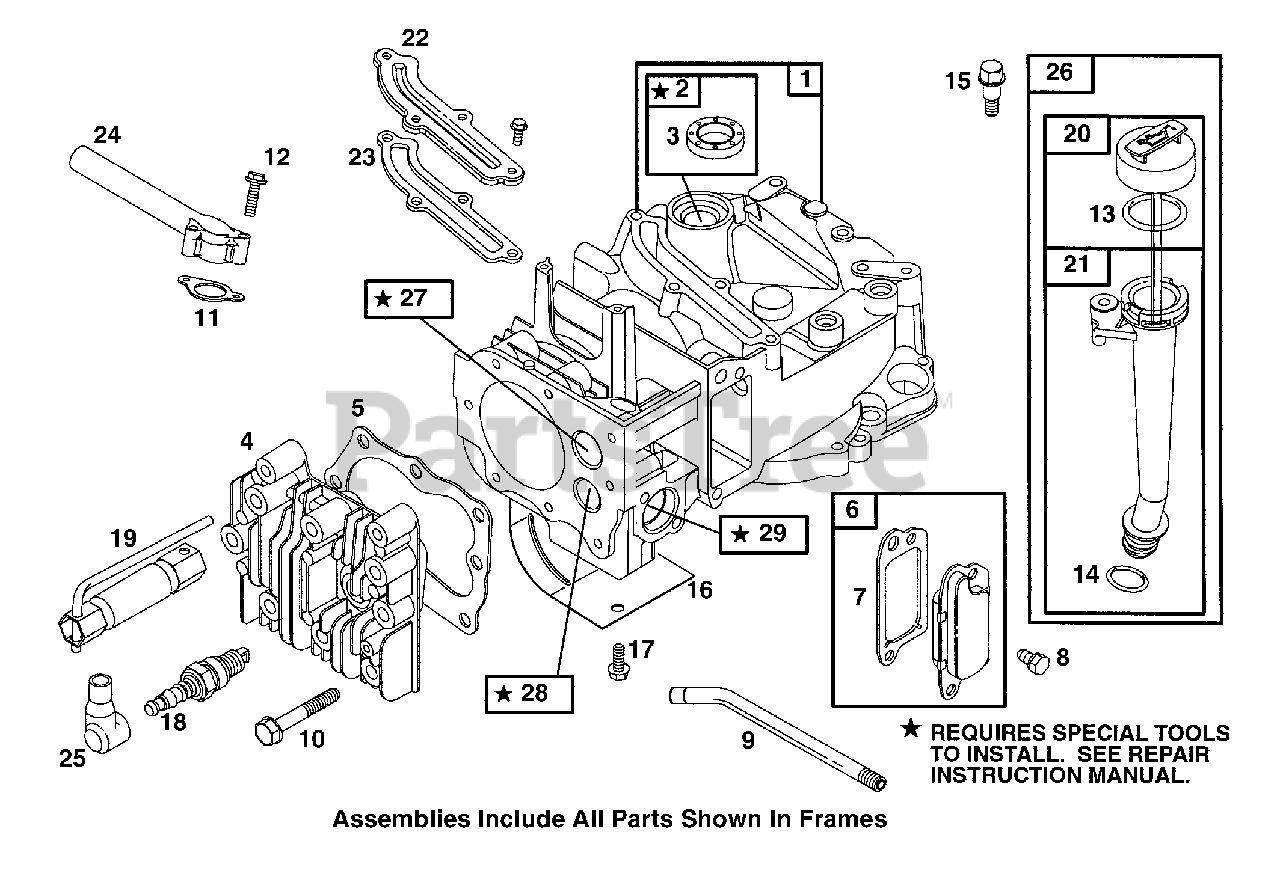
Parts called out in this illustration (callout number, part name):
1	Cylinder Assembly
2	Bushing/Seal Kit
3	Oil Seal
4	Cylinder Head
5	Cylinder Head Gasket
6	Breather Assembly
7	Breather Gasket
8	Hex Screw
9	Breather Tube
10	Hex Screw
11	Intake Gasket
12	Hex Screw
13	O-Ring Seal
14	O-Ring Seal
15	Shoulder Screw
16	Cylinder Shield
17	Hex Screw
18	Spark Plug
19	Spark Plug Wrench
20	Dipstick
21	Oil Filler Tube
22	Breather Passage Cover
23	Breather Passage Gasket
24	Intake Manifold
25	Spark Plug Elbow
26	Dipstick/Tube Assembly
27	Valve Seat
28	Valve Seat
29	Guide Bushing
